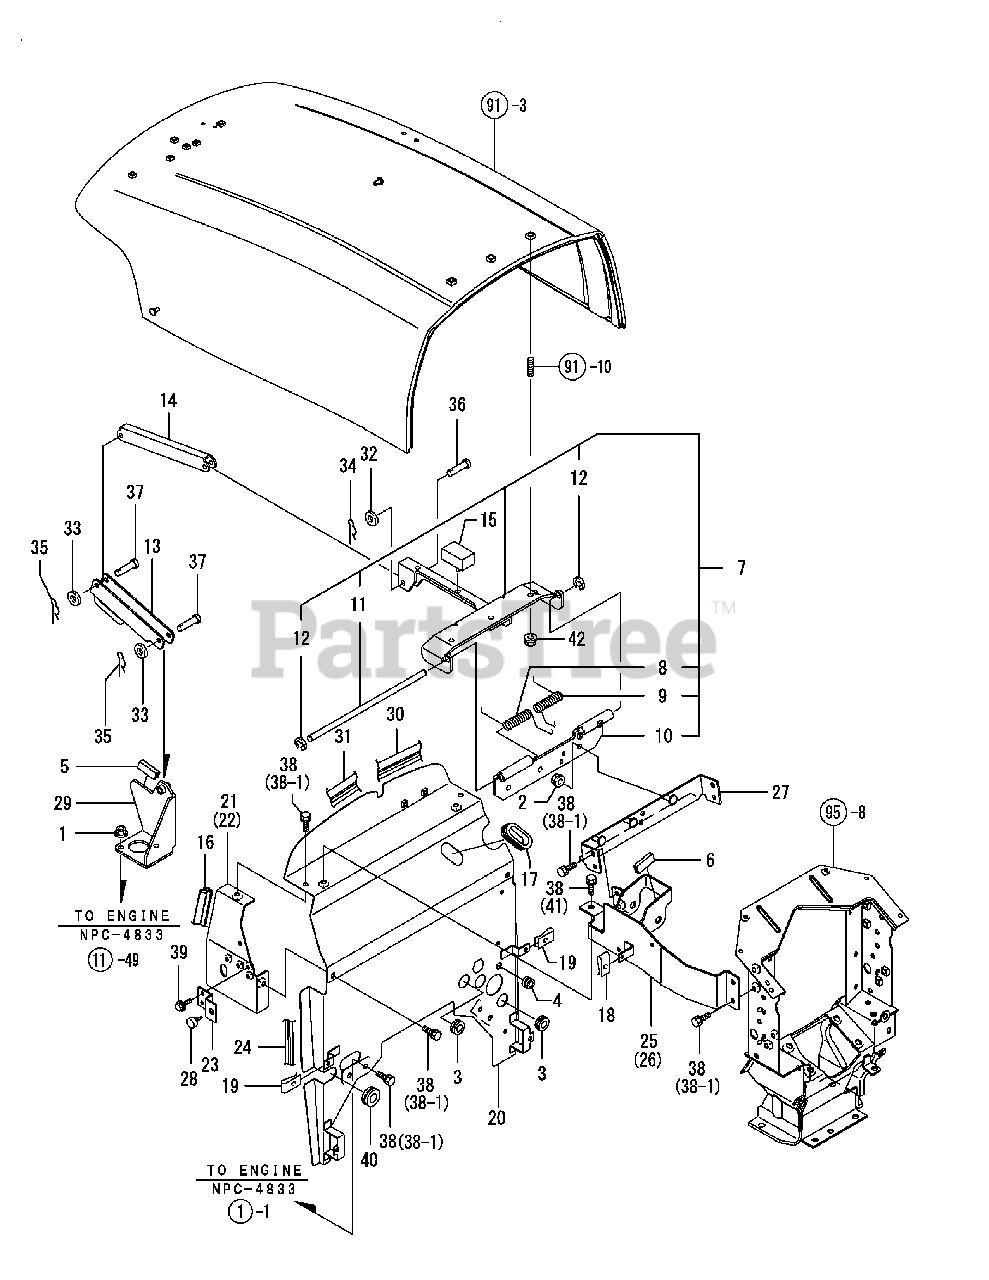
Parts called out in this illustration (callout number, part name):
1	NUT W/WASHER 8
2	NUT W/WASHER 8
3	GROMMET, 25
7	HINGE ASSY, HOOD
16	WEATHER STRIP, 180
17	GROMMET, 21X46
18	NUT, M5
19	NUT, M5
20	PLATE CMP, AIR SHIELD
21	SUPPORT L.H., CMP
22	SUPPORT R.H., CMP
25	BRACKET L CMP, TANK
26	BRACKET R CMP, TANK
27	SUPPORT CMP, HOOD
28	STOPPER, PEDAL
29	STAND CMP, HOOD
30	WEATHER-STRIP, 195
31	STRIP 250, WEATHER
32	WASHER 8, POLISHED
33	WASHER 8, POLISHED
34	SNAP PIN (JASO 8)
35	SNAP PIN (JASO 8)
38	BOLT M 8X 16 PLATED
39	BOLT M 6X 12 PLATED
41	BOLT M 8X 12 PLATED
42	NUT W/WASHER 8
